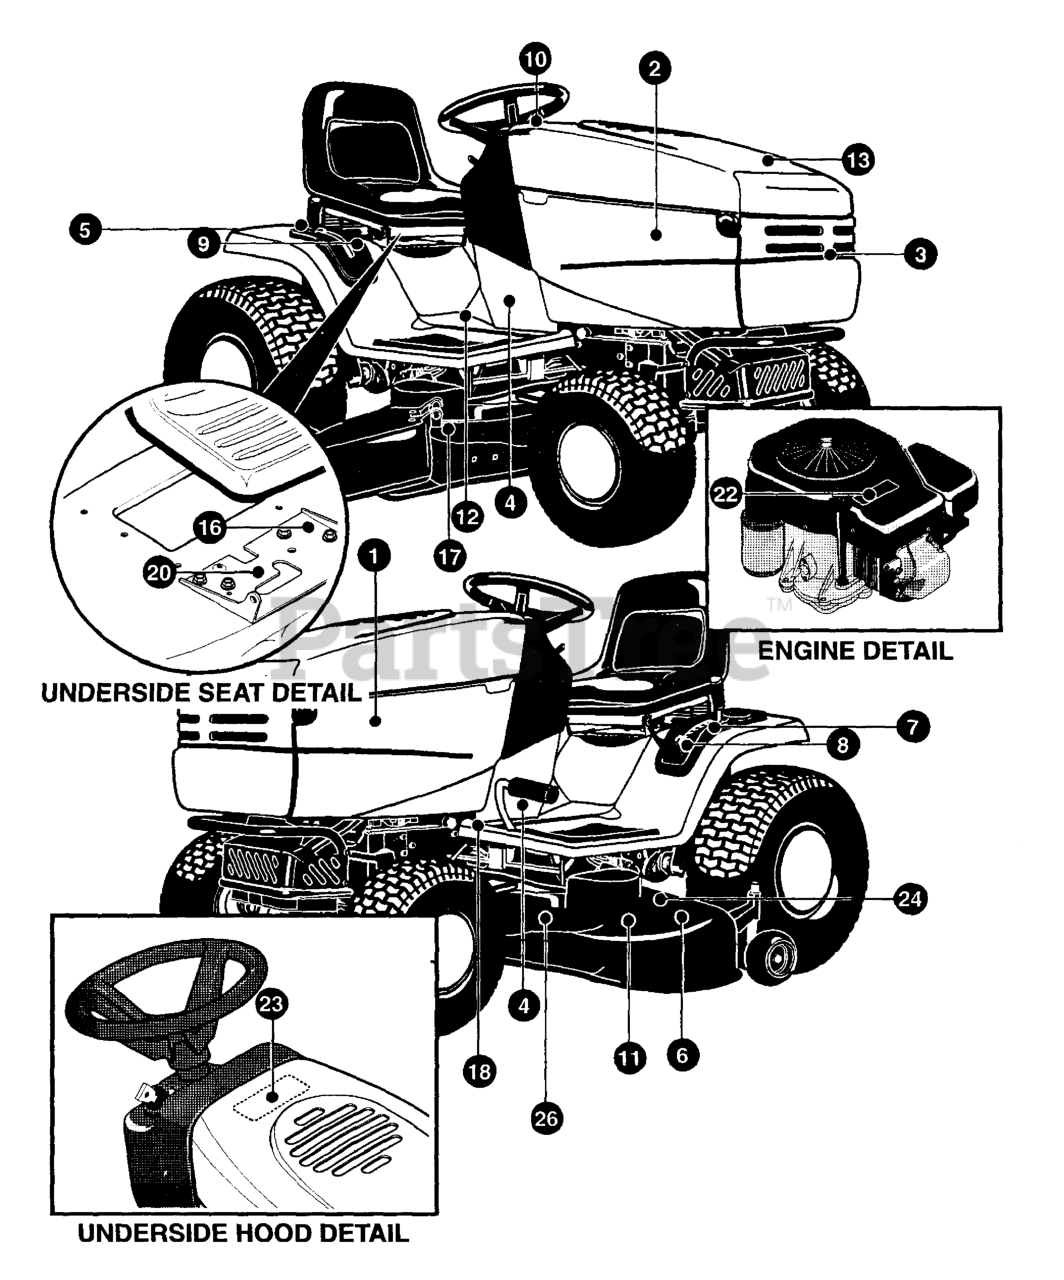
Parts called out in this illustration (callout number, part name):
1	DECAL, SCOTTS 16/42 RH
2	DECAL, SCOTTS 16/42 LH
3	DECAL, GRILLE SCOTTS
4	DECAL, KO OIL FILTRATION SYSTEM
5	DECAL, REAR SEAT DECK SCOTTS
6	DECAL, CUTTING DECK
7	DECAL, HEIGHT ADJUST 1-6
8	DECAL, DECK LEVEL
9	DECAL, CRUISE CONTROL
10	DECAL, CUST. CARE CENTER 44X6946
11	DECAL, NO STEP DOM WH/CLEAR
12	DECAL, HYDRO DOM CONS 44X4248
13	DECAL, EMBLEM HOOD SCOTTS
16	NOT A SERVICEABLE PART
17	DECAL, DOM CUT FINGER/OPEI98
18	DECAL, CLUTCH/BRAKE TOE
20	DECAL, HYDRO REL. VALVE
22	DECAL, SCOTTS 16HP KOHLER
23	DECAL, MAINT. KOHLER
24	DECAL, DECK LEVEL PROCEDURES
26	DECAL, DECK ROUTING
